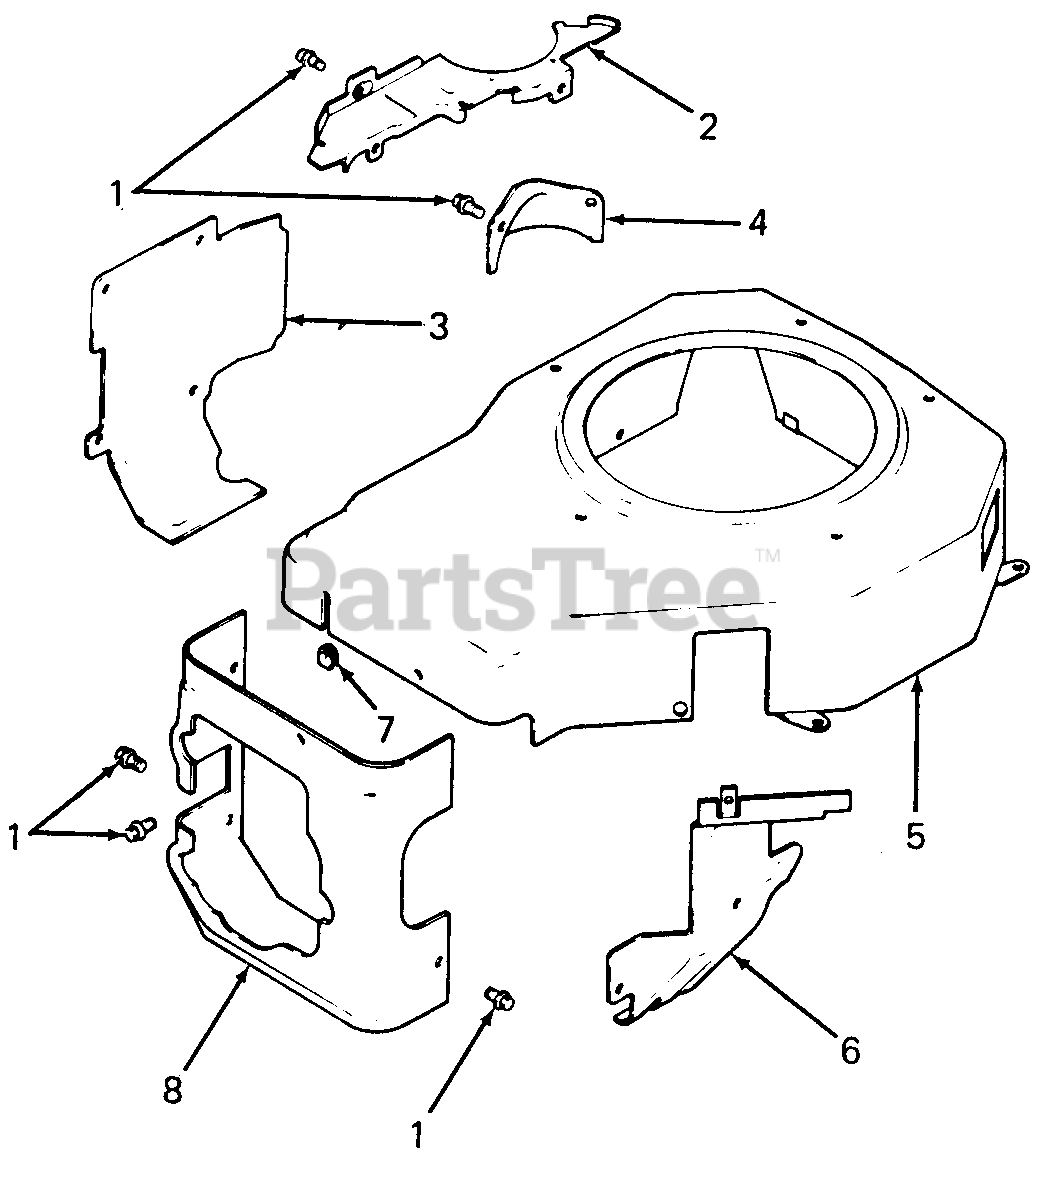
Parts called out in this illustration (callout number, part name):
1	Screw, Mounting, M5 X 0.8 X 10
2	Plate, Blower Housing
3	Baffle, Cylinder Barrel
4	Cover, Starter
5	Housing, Blower
6	Baffle, Carburetor
7	Grommet, Blower Housing
8	Baffle, Cylinder Head
